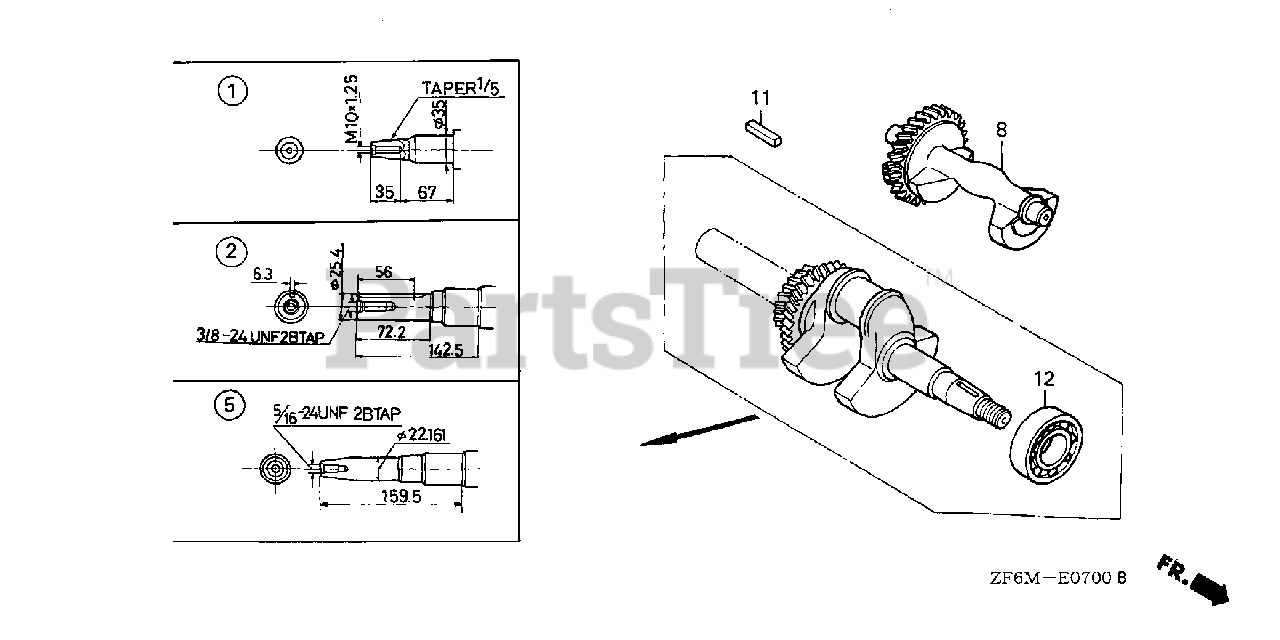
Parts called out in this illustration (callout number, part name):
1	CRANKSHAFT
8	WEIGHT, BALANCER
12	BEARING, RADIAL BALL (6207S)
